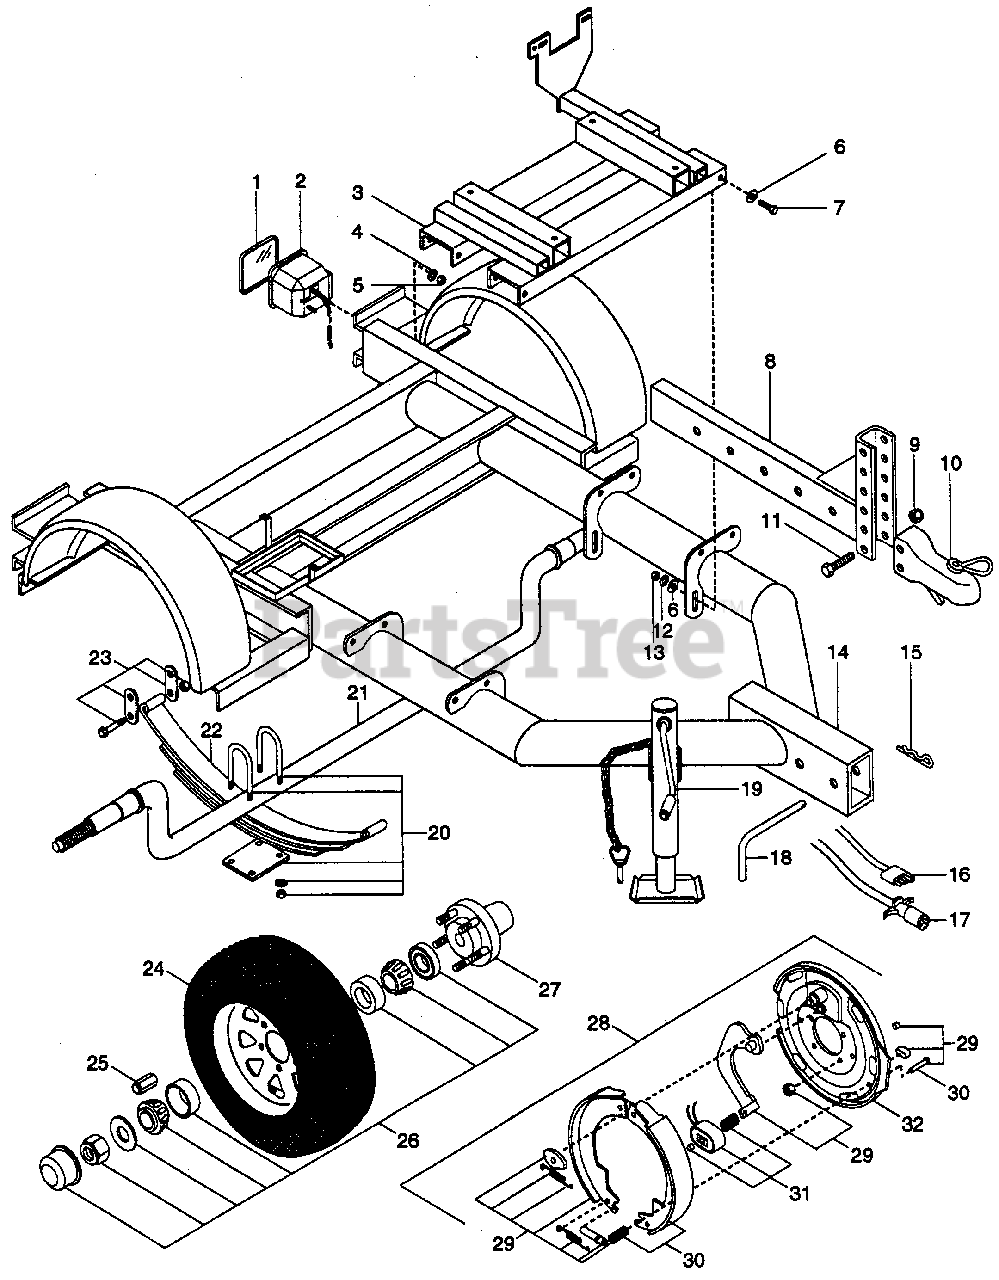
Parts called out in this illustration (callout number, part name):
1	Electric Axle 395
2	P-Tail Light LH
3	Engine Crossbrace Weld-Diesel
4	Wshr-Lock Ext. 250 ID
5	Nut .250-20 Pl
6	Wshr-Fl-Stl .563 x 1.37 x .109 Pl
7	Blt-Hex .50-13 x 2.00 Pl Gr 5
8	Tongue Weldment
9	Nut-Lk-Ctr .625-11 Pl
10	Hitch-Ring
11	Blt-Hex .62-11 x 4.25 Pl Gr 5
12	Wshr-Lock .625 x .156 Med Pl
13	Nut .50-13 Pl
14	Traillor Frame Weldment
15	Pin-Hair lnt .17 x .68 x 3.50 Pl
16	P-Wire Harness
17	Plug Connector-Trailor
18	Hitch Pin
20	U-Bolt Kit 3500# Axle STD
21	Rear Axle W/A/P
22	Spring 3500# Axle STD
23	Hardware Kit 3500# Axle STD
24	T/Whl Assy
25	Lug Nut Kit 3500# Axle STD
26	Bearing Kit 3500# Axle STD
27	Hub 3500# Axle STD
28	LH Assy Complete 3500# Electric Axle
29	LH Rebuild Kit 3500# Electric Axle
30	Lining Kit 3500# Electric Axle
31	Magnet Kit 3500# Electric Axle
32	Backing Plate Kit 3500# Electric Axle
